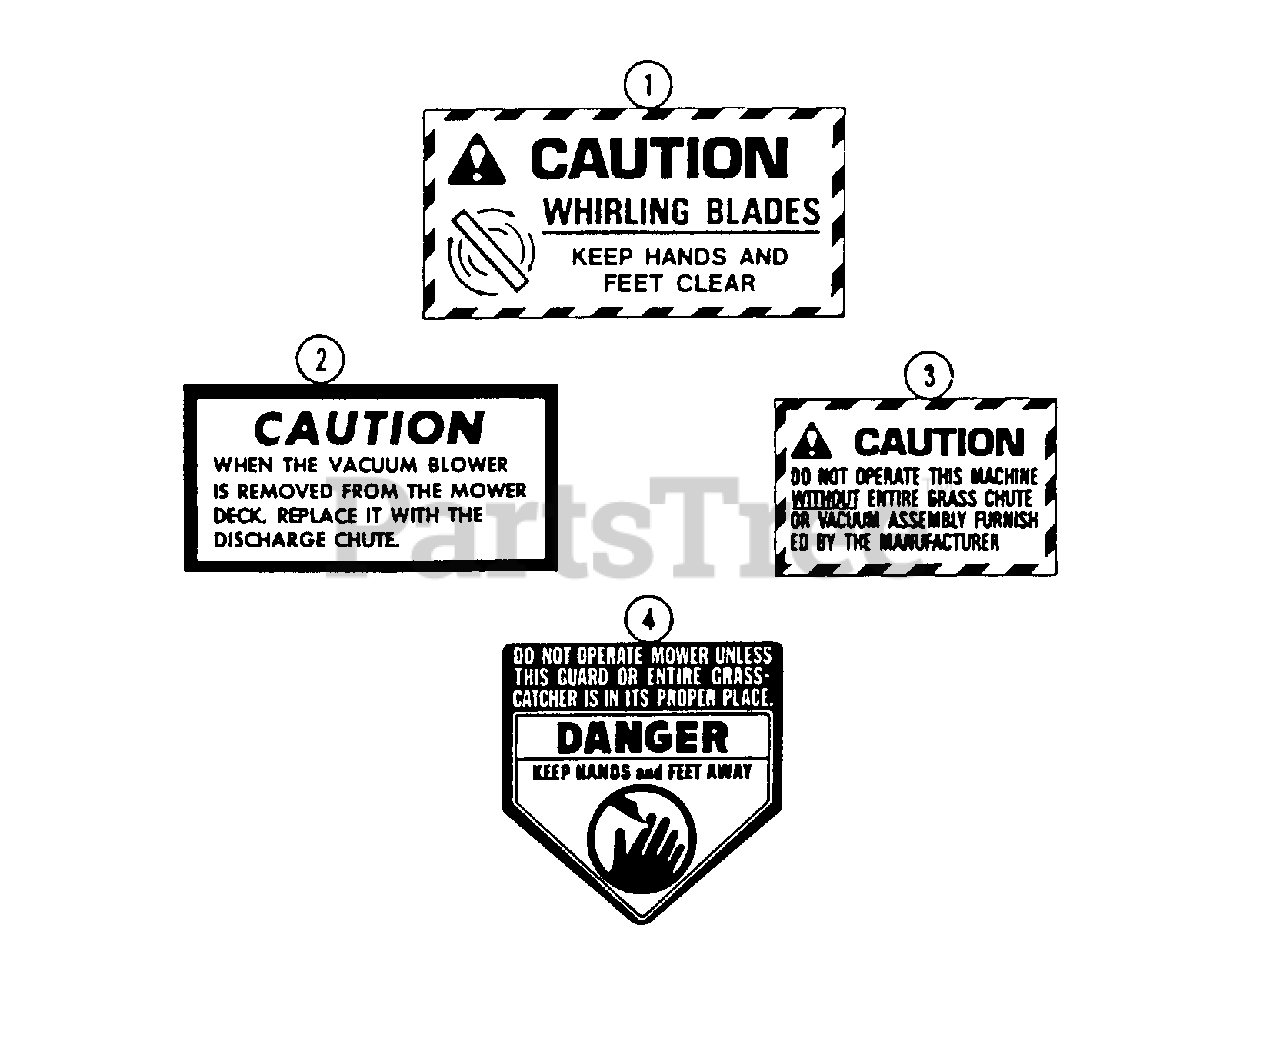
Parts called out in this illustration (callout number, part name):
1	DECAL - "Whirling Blades"
2	DECAL - "Caution" discharge chute
3	DECAL - "Caution" grass chute
4	DECAL - "Danger"
